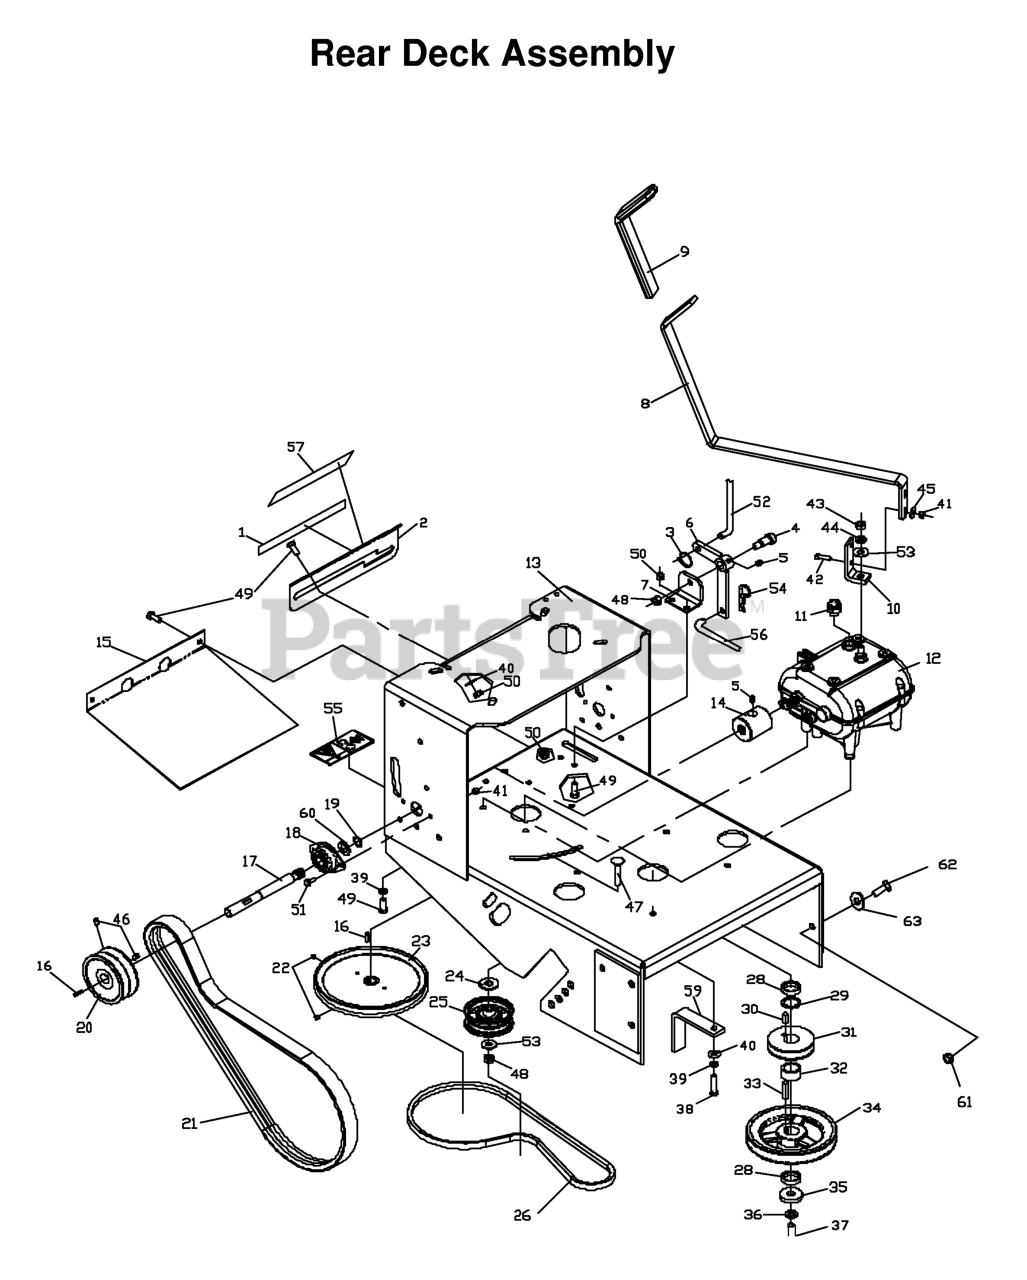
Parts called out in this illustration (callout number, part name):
1	DECAL, SHIFTER
2	SHIFTER PLATE
4	SB 12C X 34
5	ZERK
7	BRACKET-BELLCRANK-BLACK
8	SHIFTER ARM
9	SHIFTER GRIP
10	SHIFTER BRACKET
11	SWITCH, TRANS
12	TRANSMISSION WB
13	REAR DECK W/DECALS
15	LOWER BELT SHIELD
16	KEY, #9 WOODRUFF
17	DRIVE SHAFT
19	RETAINER RING
20	PULLEY, DRIVE (36 & 48)
21	BELT, DRIVE 36/48
22	SETSCREW, 1/4-20 NYLOC
23	PULLEY, INPUT
24	WASHER 1/2 FLAT
25	IDLER PULLEY
26	BELT, TRANSMISSION
27	BELT GUIDE
29	BUSHING, 10GA MACHINERY
30	SQUARE KEY - 1/4 X .5
33	KEY 1/4 SQ X 1 1/8
34	PULLEY, ENGINE
35	SPINDLE WASHER
36	WASHER 7/16 LOCK
37	HCS 7/16F X 1 1/2
38	HEX SCREW 5/16 X 1.75
39	WASHER.LOCK.HVY.HLCL.SPR.5/16
40	WASHER 5/16 FLAT
41	NUT 1/4C CENTER LOCK
42	HCS 1/4C X 1
44	SLW 3/8 STD
45	WASHER 1/4 FLAT
46	SET SCREW 5/16 NYLOC
47	RHSNB 3/8C X 2
48	NUT 3/8C CENTERBLOCK
49	HCS 5/16C X 3/4
50	NUT 5/16C CENTERLOCK
51	HCS 1/4C X 5/8
53	WASHER 3/8 FLAT
54	HAIRPIN #4
55	DECAL, BELT DRIVE
56	BLADE ROD 48"
57	DECAL, CLUTCH
59	BELT GUIDE - LONG
60	BELT GUIDE, SHORT
61	NUT 7/16C CENTERLOCK
62	HCS 7/16C X 1 1/2
63	WASHER 7/16 FLAT ZD
539102048	BLADE ROD 36"
539103462	BELT GUIDE - LONG
